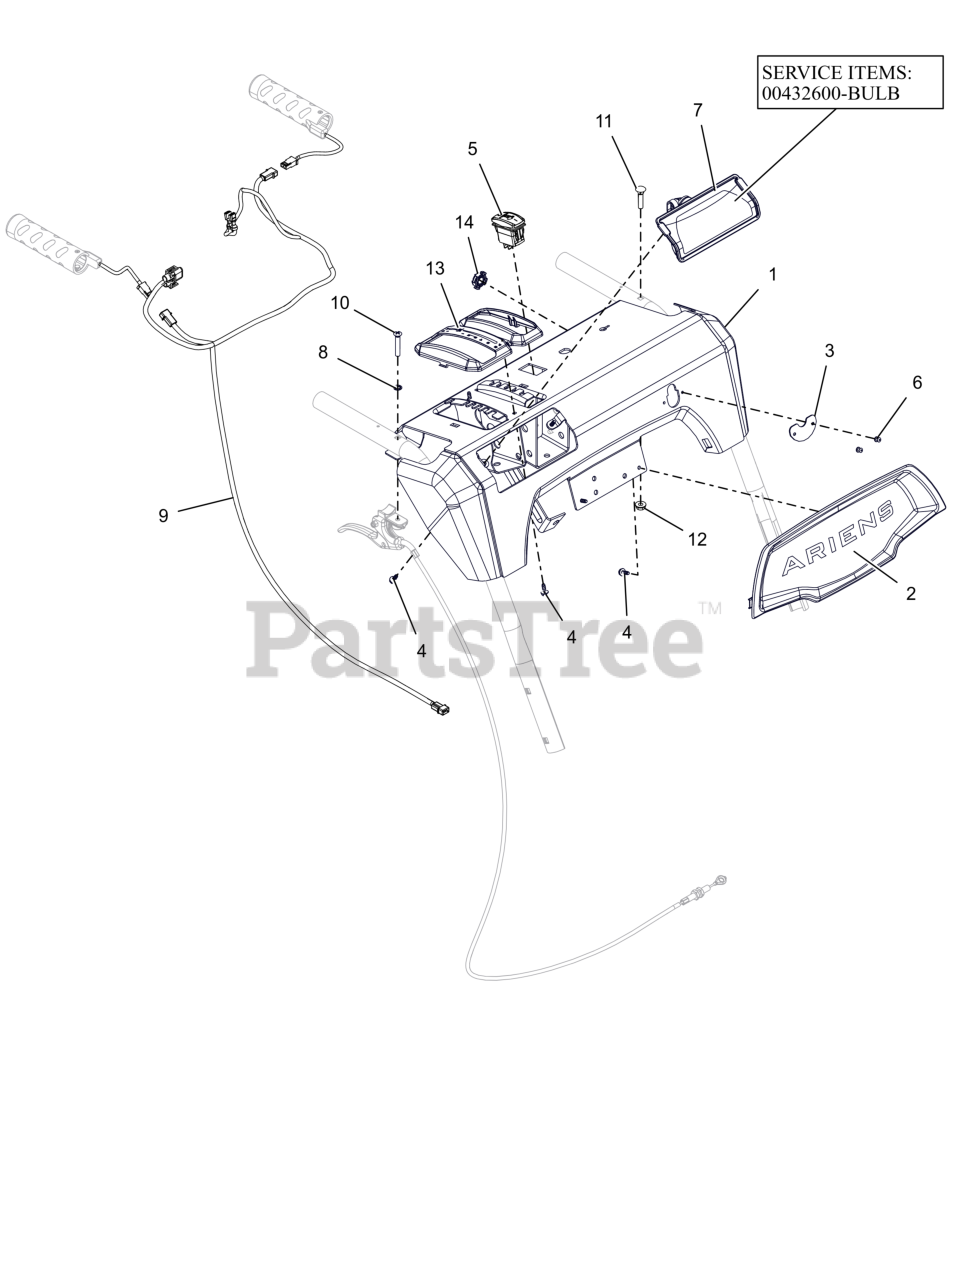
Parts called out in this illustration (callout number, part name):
1	WLDMT, DASH PANEL - FRICTION ID
2	BEZEL, DASH - ARIENS LG DASH
3	COVER, DASH BRKT, ID
4	SCR, PLASTIC #10X.50
5	SWITCH,ROCKER SPST-ON/OFF
6	RVT-POP #43 .125X.313 STL ZINC
7	HEADLIGHT ASY, HALO 20W 2SHOT
8	WSHR-LK-INT .250 TH TYA
9	HARNESS, LIGHT & WARMER
10	SCR,OVAL .25-20X1.50 ZCC
11	BLT-RDHDXLSQNK.25-20X1.25 G5ZC
12	NUT-LK-CTR-FLG .25-20 ZC120
13	BEZEL, SHIFT - FRICTION SNOW
14	CRANK BUSHING, NYLON CHUTE BK
